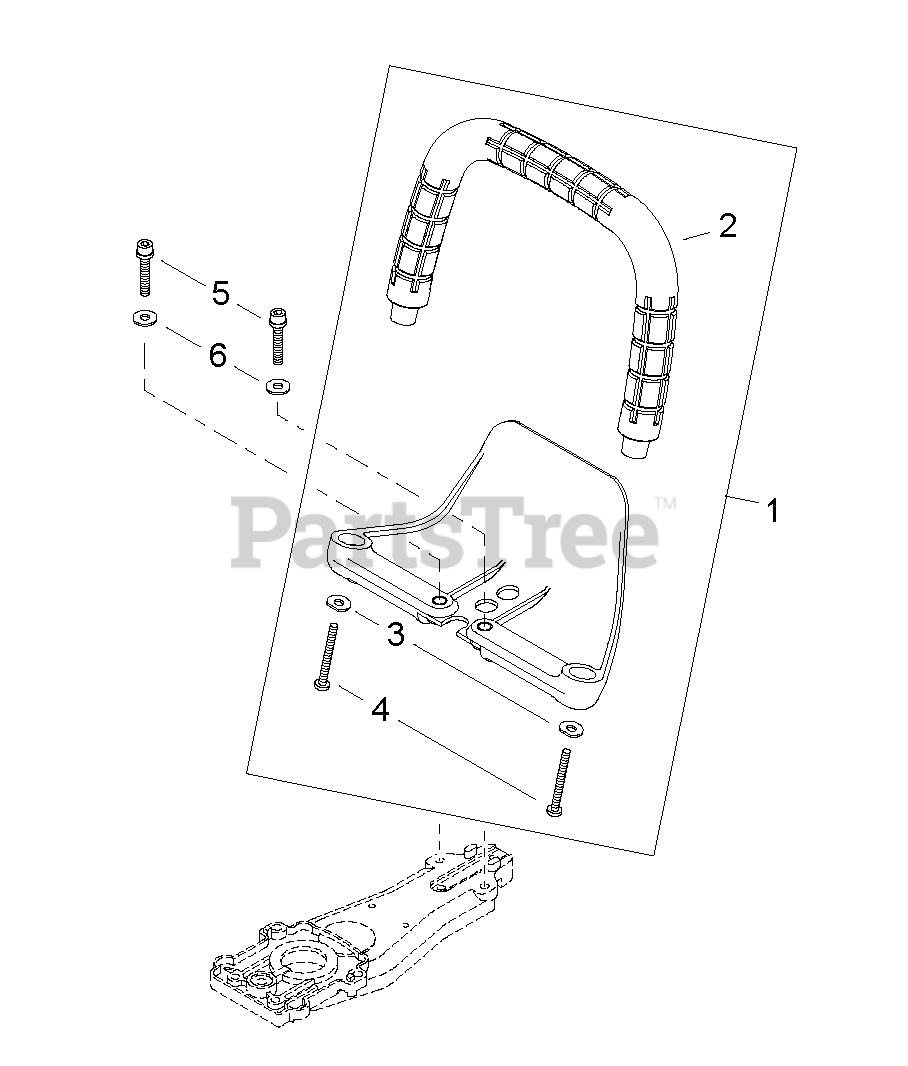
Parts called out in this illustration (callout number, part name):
1	HANDLE ASSY - FRONT
2	HANDLE - FRONT
4	SCREW - 5 -- TAPPING
5	SCREW - 6X35
